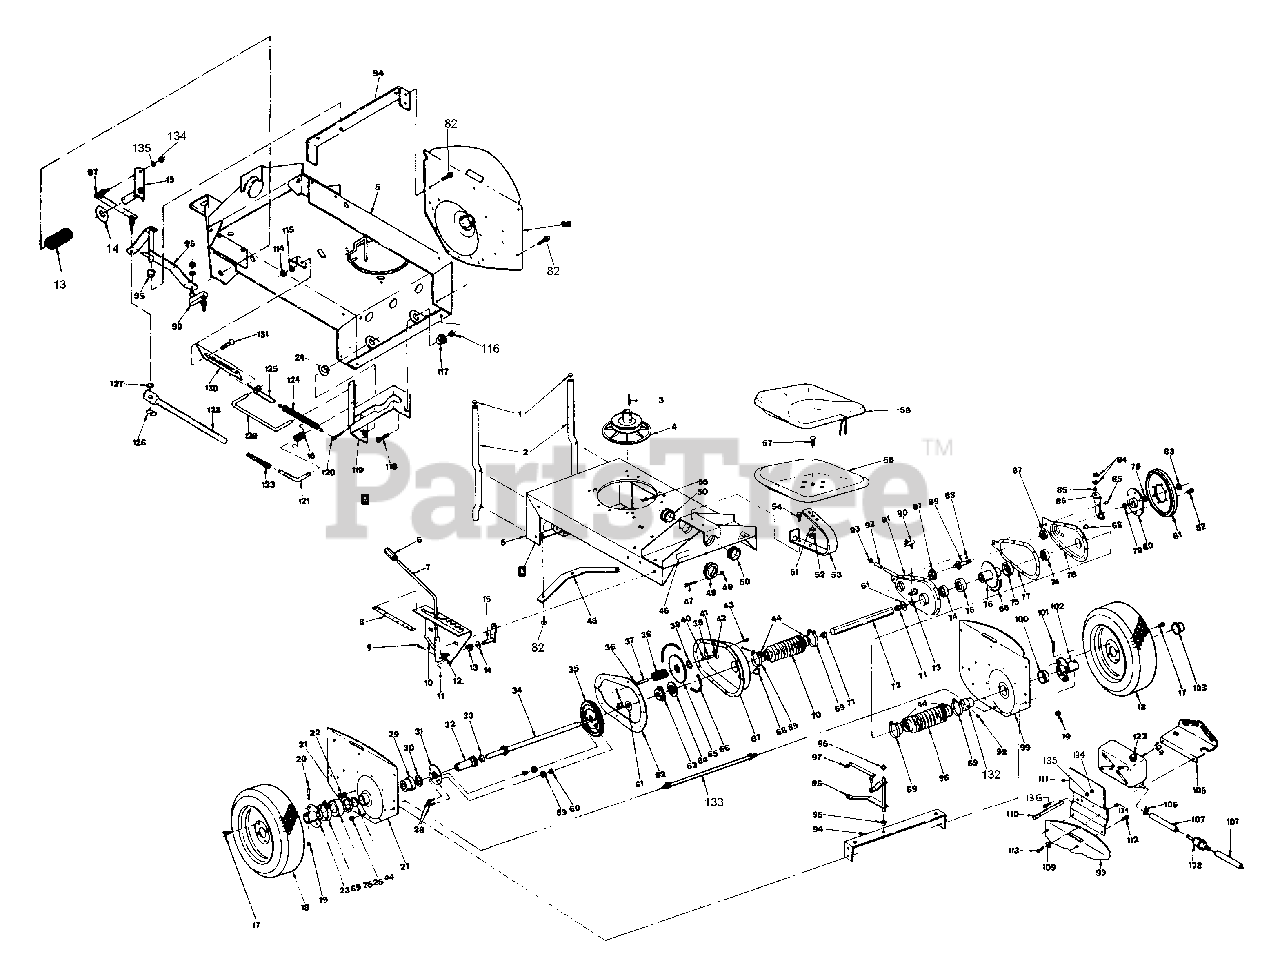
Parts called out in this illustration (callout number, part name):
1	Cap
2	Bumper
3	Key
4	Drive Disc
5	Main Case
6	Grip
7	Shift Handle
9	Clevis Pin
10	Shift Detent
11	3/32 x 3/4 Cotter Pin
12	Thrust Washer
13	Spring
14	Thrust Washer
15	Shift Handle Arm
16	Spring
17	Lug Bolt
18	Wheel and Tire Ass'y.
19	5/16-24 Lock Nut GR5
20	Wheel Bolt, R.H.
21	Oil Seal
22	5/16 Flange Lock Nut
23	Right Hand Wheel Hub
24	Thrust Washer
25	5/16-24 Lock Nut
26	Seal Cap, R.H.
27	Fender, R.H.
28	5/16-24 x 1-5/8 HH Lock Cap Screw
29	Bearing
30	Thrust Washer
31	Differential Plate
32	KIT, Includes Short & Long Axle
33	SPACER, Differential (1.25" ID x .425 Wide)
34	KIT, Includes Long & Short Axle
35	63T, 10P Gear
36	5/16 Belleville Washer
37	Spacer
38	Gear, 11T, 10P
39	Retaining Ring
40	Idler Bolt
41	O-RING, 5/16"
42	5/16 Internal Tooth Lock Washer
43	1/4-20 x 5/8 Self Tapping Screw
44	Seal Ring
45	Hitch Plate
46	Name Plate
47	5/16-24 x 2-1/2 Hex Head Cap Screw
48	Tube Clamp
49	5/16-24 Flange Lock Nut
50	Grommet
51	7/16 Lock Washer
52	7/16-14 Hex Nut
53	Seat Spring
54	3/8-16 x 1 Hex Head ST. Screw
55	Washer (Tech Engine)
56	Seat Pan
57	7/16-14 x 1 Carriage Bolt
58	SEAT
59	12T, 12P Gear
60	Pinion Spacer
61	Flange Washer
62	Gasket
63	Sprocket
64	Washer
65	Sprocket
66	Chain
67	Case
68	Plastic Plug
69	Boot Clamp
70	Boot
71	Bearing
72	ASSEMBLY, Drive Hex Tube
73	Nylon Washer
74	Needle Bearing
75	Nylon Thrust Washer
76	Hub and Sprocket Str.
77	Gasket
78	Cover, Left Hand
79	Belleville Washer
80	Hub
81	DISC, Driven (R/B 7018782)
82	5/16-18 x 5/8 HWST
83	5/8-18 Hex Lock Nut
84	Washer
85	Split Spacer
86	Brake Lever
87	Bearing
88	KEY, 1/8 x 5/8" Woodruff
89	Sprocket and Shaft
90	Shift Link, Short
91	Cover, Right Hand
92	Roller
93	Retaining Ring
94	Cross Brace
95	Nylon Bearing
96	Shift Arm
97	Shift Link, Long
98	Grease Fitting
99	Fender, Left Hand
100	CAP, Seal L.H. 3/4"
101	Axle Bolt, Left Hand
102	Hub, Left Hand
103	Hub Cap
104	5-Quart Tank
105	Front Bracket
106	Hose Clamp
107	Fuel Hose
108	Filter
110	Tank Brace
111	Bracket, Back
112	Hex Cap Screw ST.
113	5/16-24 x 5/8 Hex Head Cap Screw
114	3/8-16 Hex Nut
115	3/8 lock Washer
116	5/16-18 Hex Nut
117	Yoke Bearing
118	5/16-18 x 1 Self Tapping Screw
119	LIFT, Yoke
120	3/16 x 3/4 Cotter Pin
121	Rod
122	Gas Cap
123	Spring, 8 H.P. Only
124	Spring
125	Clutch Clovis
126	5/16-24 "T" Nut, 8 H.P. Only
127	5/16 Internal Tooth Lock Washer
128	Tube, 8 H.P. Only
129	Clutch Rod
130	Rod Guide
131	3/8-16 x 3/4 Carriage Bolt
132	Bearing, Fender
133	Tie Rod
134	NUT, 5/16-24 Hex
135	5/16" SLW
136	5/16"-24x1" HHCS
